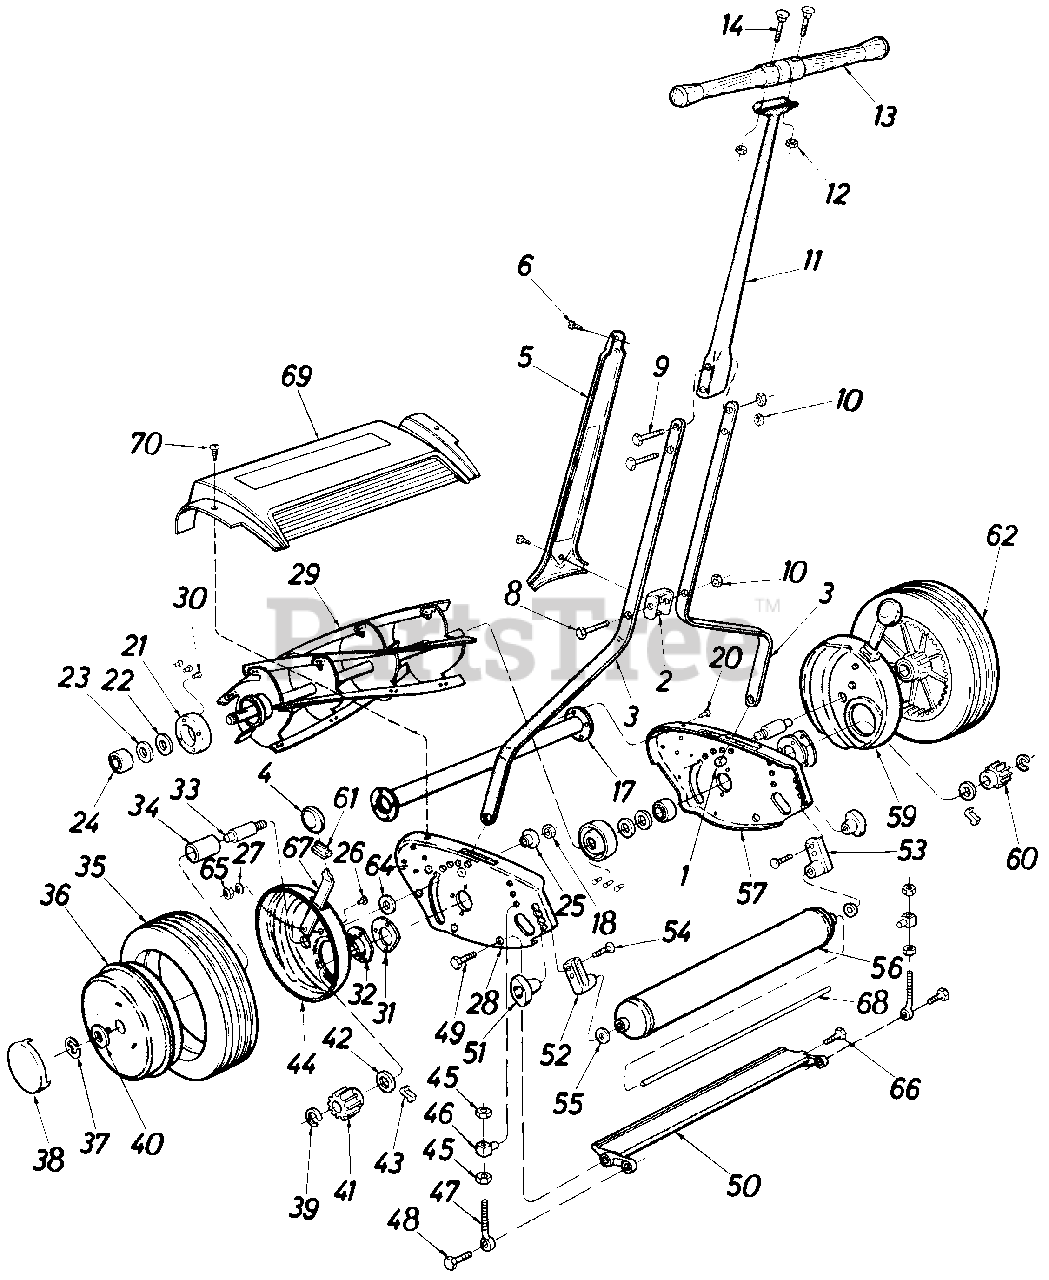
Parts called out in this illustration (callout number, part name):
1	Trunnion
2	Spacer
3	Handle Brace 16"
4	Knob Wheel Adjust.
5	Handle Panel
6	Ph. Hd. Scr. #10 x .38 Lg.
8	Hex Scr. 5/16-18 x 2.50" Lg.*
9	Hex Scr. 5/16-18 x 2.25" Lg.*
10	Hex Nut 5/16-18 Thd.
11	Handle Shaft
12	Hex Nut 1/4-20 Thd.
13	Cross Handle
14	Carriage Bolt 1/4-20 x 1.75" Lg.*
17	SpacerTube Ass'y.
18	Hex L-Nut 5/16-24 Thd.
20	Rivet 3/16 Dia. x 3/8" Lg.
21	Retainer
22	Felt Washer
23	Felt Retainer
24	Bearing
25	Bushing
26	Hex Scr. #10-32 x 3/8" Lg.
27	Washer
28	End Plate Ass'y. L.H.
29	18" Reel Ass'y.
30	Rivet 3/16 Dia. x 13/32" Lg.
31	Retainer
32	Pinion Housing
34	Bearing
36	Wheel Ass'y.
37	Retaining Ring
38	Hub Cap
39	Retaining Ring
40	Fl-Wash. .38" I.D. x 1.25" O.D.
41	Pinion Gear L.H.
42	Felt Washer
44	Gear Housing Ass'y. L.H.
45	Hex Nut 3/8-24 Thd.*
46	Trunnion
47	Screw Cutter Bar Adj.
48	Screw Rear
49	Screw Pivot (R.H. Thd.)
50	Cutter Bar
51	Roller Adj. Knob
52	Roller Brk't. L.H.
53	Roller Brk't. R.H.
54	Roller Adj. Bolt
55	Fl-Wash. .312" I.D. x .75" O.D.*
56	18" Roller
57	End Plate Ass'y. R.H.
59	Gear Housing Ass'y. R.H.
60	Pinion Gear R.H.
61	Dust Cover
62	Wheel Ass'y. Comp. 9 x 1.75
64	Washer
65	Hex Nut #10-32 Thd.
66	Screw Cutter Bar (L.H. Thd.)
67	Spring and Trunnion Ass'y.
68	Roller Shaft
69	Plastic Cover
70	Self-Tapping Scr. #10 x 1/2"
